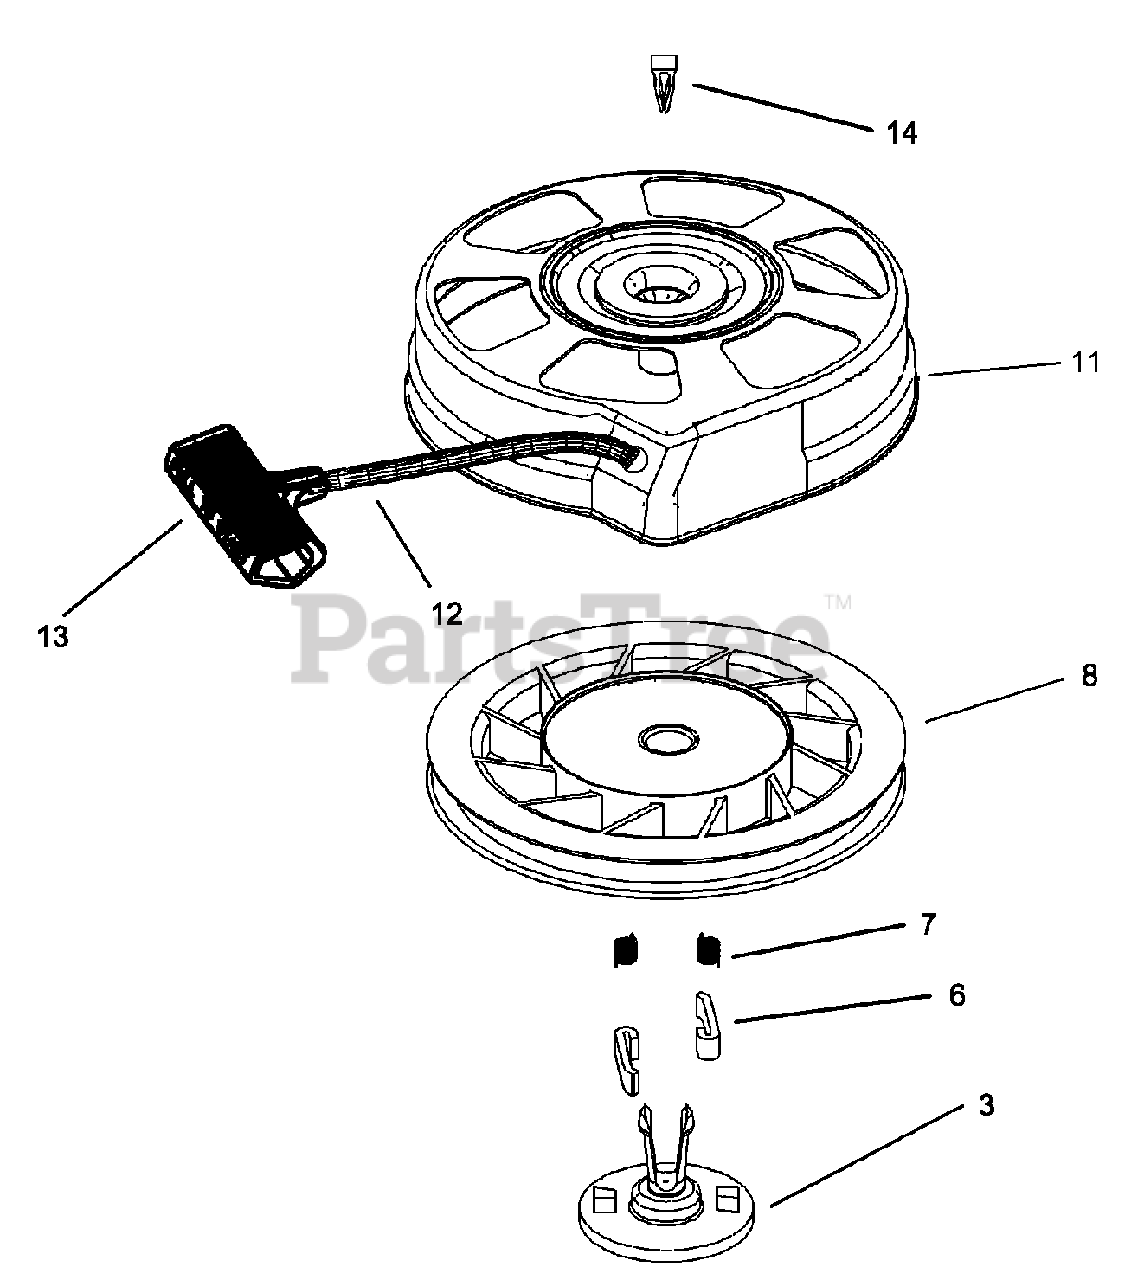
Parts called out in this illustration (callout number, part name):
3	Retainer
6	Dog-Starter
7	Spring-Dog
8	Pulley and Rewind Spring ASM
11	Housing Assembly-Starter
12	Starter Rope ( 98IN X 9/64IN dia.)
13	Handle-Starter
14	Spring Clip
